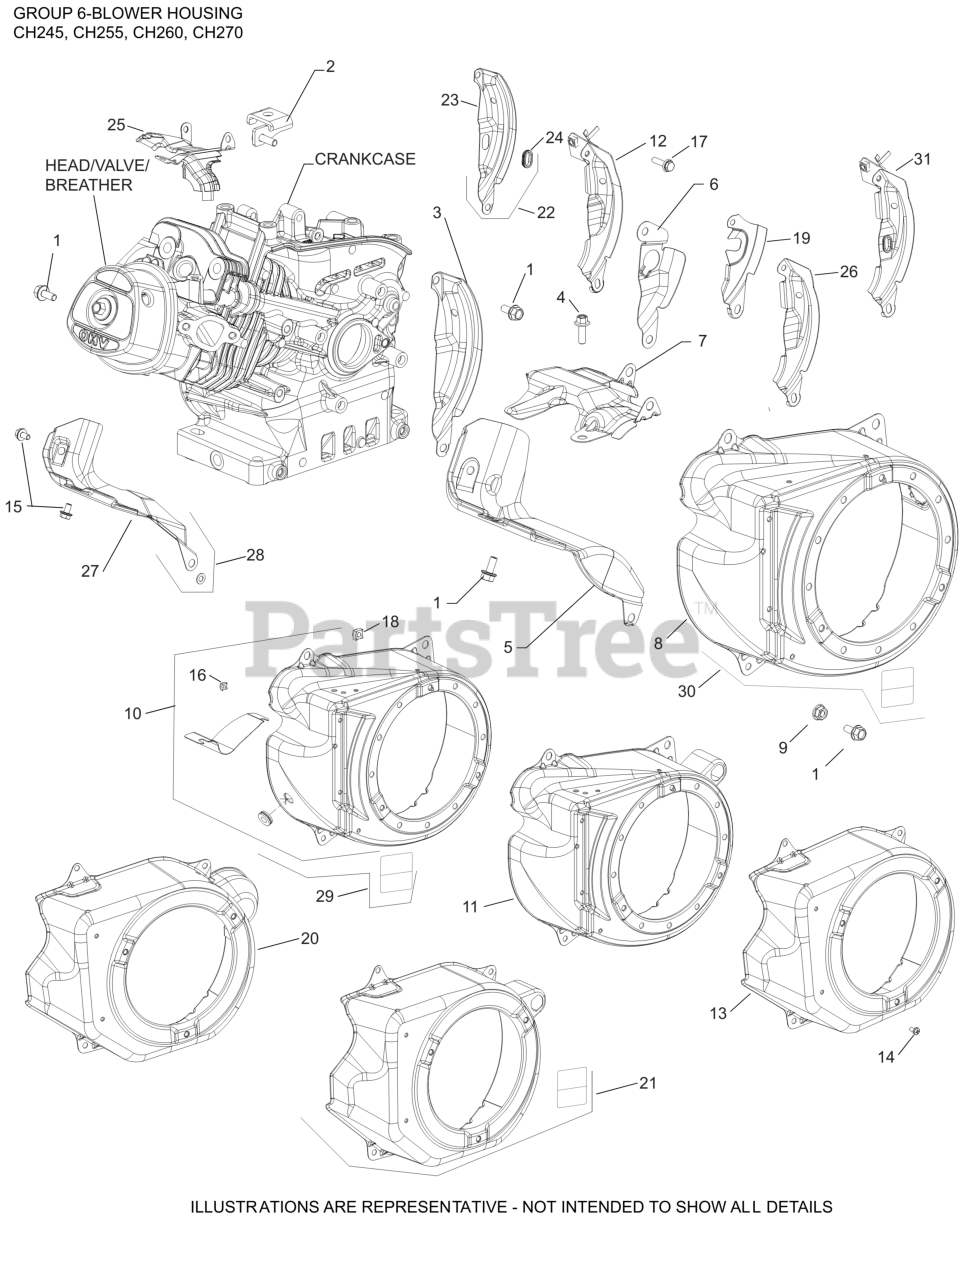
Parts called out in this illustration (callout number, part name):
1	SCREW, HEX FLANGE (M6)-USE 25 086 433-S
3	SHIELD, FLYWHEEL
4	SCREW, M6 X18
5	SHIELD, CYLINDER HEAD
7	SHIELD, UPPER HEAT
9	NUT, HEX FLANGE (M6) - USE 14 100 16-S
10	KIT, BLOWER HOUSING
